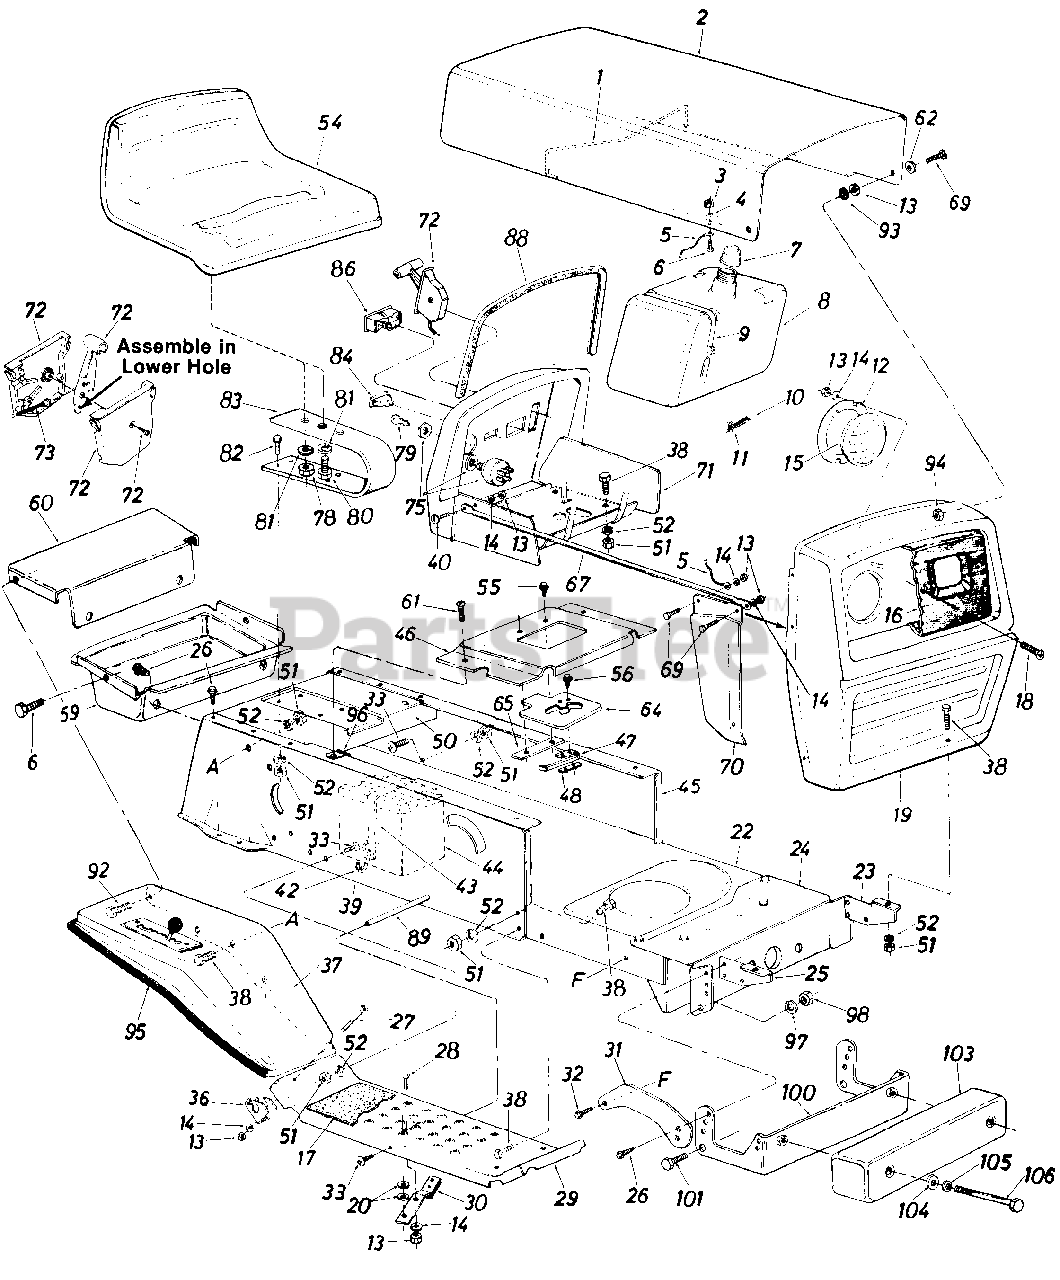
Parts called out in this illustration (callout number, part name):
1	Hood Spring
2	Hood
3	Hex Sems Nut #10-24 Thd.
4	Fl-Wash. .281" I.D. x .62" O.D. x .051
5	Hood Stop 7" Lg.
6	Truss Hd. Scr. #10-24 x 1/2" Lg.*
7	Fuel Cap Gauge
8	Fuel Tank
9	Tie Strap
10	Fuel Line
11	Hose Clamp
12	Headlight Retainer
13	Hex Nut 1/4-20 Thd.
14	L-Wash. 1/4" I.D.
15	Headlight
16	Bezel
17	Foot Pad
18	Truss Scr. #10-24 x .62" Lg.
20	Fl-Wash. .28" I.D. x .75" O.D. x .06
22	Lower Frame
23	Grille Mount Brkt.-L.H.
24	Front Pivot Brkt.
25	Grille Mount Brkt.-R.H.
26	Hex Wash. Hd. AB-Tap Scr. 5/16 x .75" Lg.
27	Truss Hd. Scr. 1/4-20 x 1.75"
28	Carriage Bolt 1/4-20 x .62"
29	Running Board
30	Blade Brake Ass'y.
31	Weight Brkt. Tie Strap
32	Hex Self-Tap Scr. 3/8-16 x .88" Lg.
33	Truss Mach. Scr. 5/16-18 x .75" Lg.
36	Fender Clamp
37	Fender
39	R.H. Side Frame
40	Hex Bolt 1/4-20 x .62" Lg.
42	Battery Strap Hook
43	Strap
44	12-V Battery
45	L.H. Side Frame
46	Shift Cover
47	Reverse Safety Switch
48	Insulator Nut Plate
50	Hitch Plate
51	Hex Nut 5/16-18 Thd.
52	L-Wash. 5/16" I.DZ
54	Seat Ass'y.
55	Truss Mach. Scr. 1/4-20 x .75" Lg.
56	Truss Mach. Scr. #10-24 x .50" Lg.
59	Tool Tray
62	Fl-Wash. .296 I.D. x .62 O.D.
64	Gear Selection Plate
65	Clamping Plate
67	Grille Support Rod
69	Truss Hd. Scr. 1/4-20 x .75" Lg.*
70	R.H.-Grille Side Panel
71	Dash Panel Ass'y.
72	Throttle Control Box Ass'y.
73	Throttle Control Wire
75	Ignition Switch
78	Hex Nut 1/2-13 Thd.
79	Ignition Key
80	Hex Bolt 1/2-13 x 1.00" Lg.
81	L-Wash. 1/2" I.D.
82	Hex Bolt 5/16-18 x 1.00"
83	Seat Spring
84	Light Switch
86	Ammeter
88	Molding Strip 27" Lg.
89	Running Board Rod
92	Thread Rolling Scr. 1/4-20 x .50" Lg.
93	Rubber Wash. 1/2" I.D. x 1.0 O.D. x .25"
94	Hex Sems Ins. L-Nut 1/4-20 Thd.
95	Trim Strip
96	Speed Nut 10Z
97	L-Wash. 7116" I.D.
98	Hex Nut 7/16-14 Thd.
100	Weight Brkt. Ass'y.
101	Hex Bolt 7/16-14 x 1.0" Lg.
103	Counterweight-38#
104	Fl-Wash. .39" I.D.
105	Bell-Wash. .39" I.D.
106	Hex Bolt 3/8-16 x 4.5" Lg.
